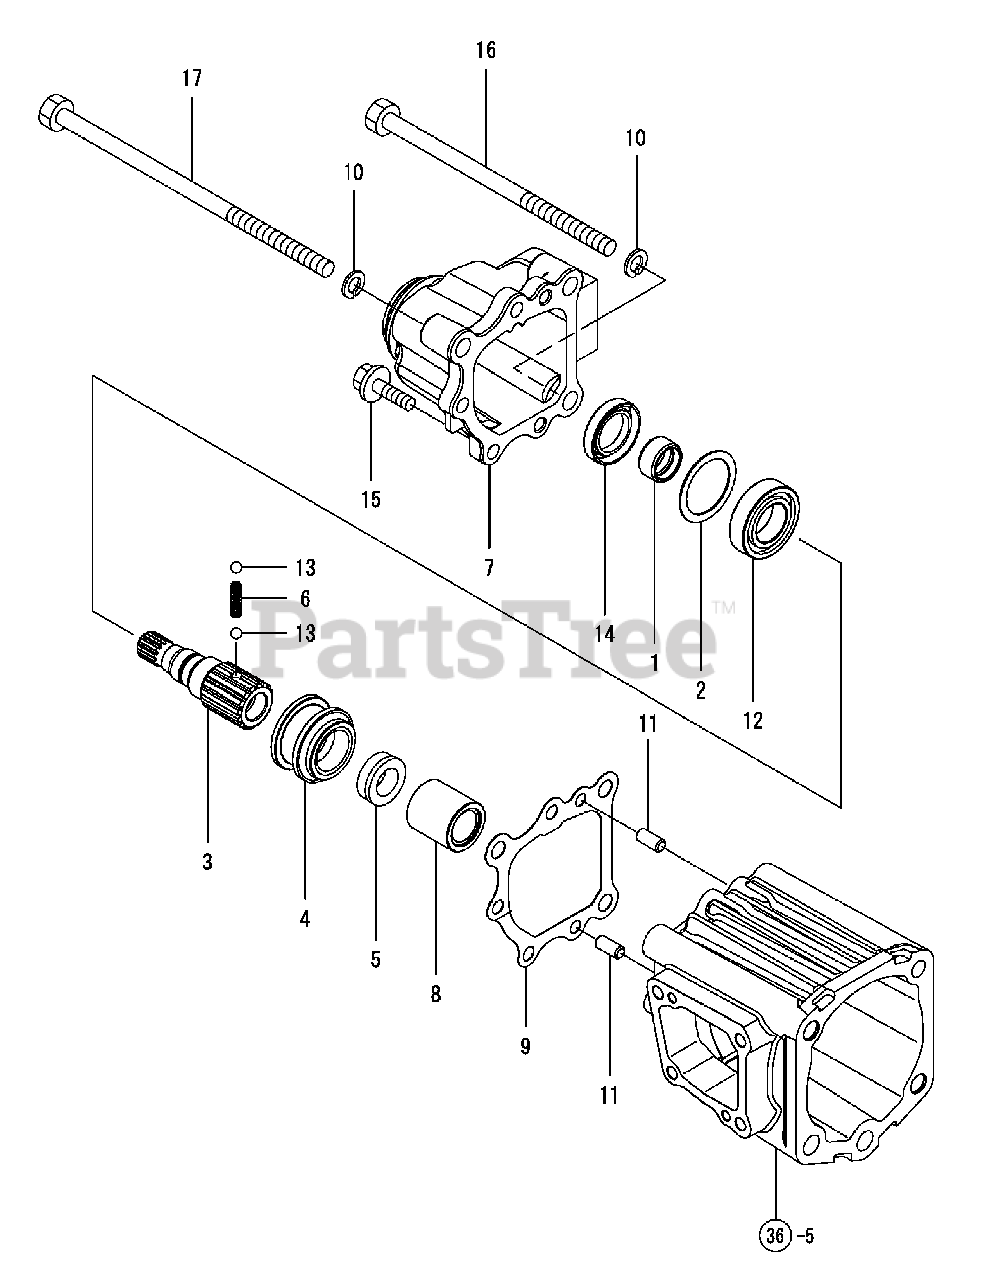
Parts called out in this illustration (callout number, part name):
1	SLEEVE SI 202513
2	WASHER, 36X46X1
3	SHAFT, FRONT DRIVE
4	COLLAR, SHIFT FRONT
5	COLLAR, SPLINE FRONT
8	SPACER, 20X33X285
9	PACKING, FRONT COVER
11	PARALLEL PIN 8X 16
12	BALL BEARING 6005
13	BALL 1/4, STEEL
15	BOLT M 8X 30 PLATED
